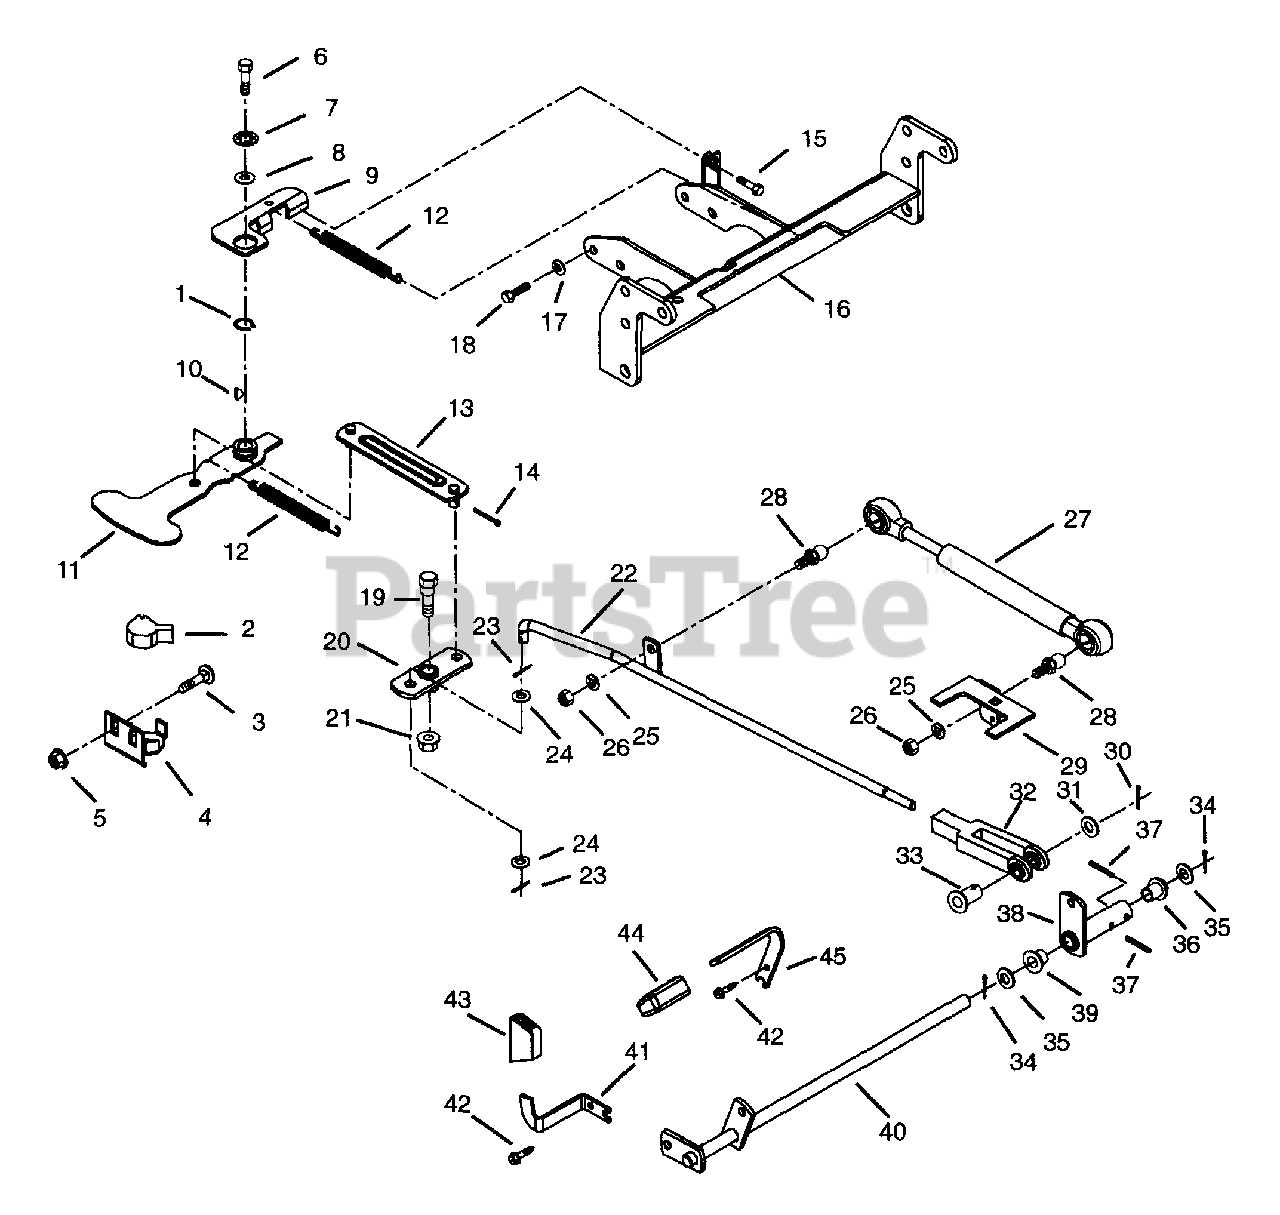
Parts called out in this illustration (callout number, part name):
1	RG-RTNG-EXT .875X.042
3	BLT-RDHDSQNK .312-18X.62SHTPL
4	MOUNT - MAGNET
5	NUT-LK .312-18 GR A PL
6	BLT-HEX .25-20X1.50 PL GR5
7	WSHR-LK-EXT. 250 ID
8	WSHR-FL-STL.312X.734X.065PL
9	ARM, NEUTRAL
10	KEY-WDRF .125X.500X.203 SAE 3
11	ARM, NEUTRAL CONTROL
12	SG-TENS .085X.60X5.13 WLD8.3
13	LINK, SHIFT
14	PIN-COTR .12X.75 PL
15	BLT-HEX .31-18X.75 PL GR2
16	MOUNT, TORQUE
17	WSHR-LK .312X.097 PL HVY
18	BLT-HEX .31-18X.75 PL GR5
19	BLT-SHLDR .38-16X1.25
20	BELLCRANK - SHIFT
21	NUT-LK-CTR .375-16 GR A PL
22	ROD - SHIFT
23	PIN-COTR .09X.75 PL
24	WSHR-FL-STL.406X.812X.065PL
25	WSHR-LK .312X.097 PL HVY
26	NUT-HEX .312-18
27	DAMPER - HYDRAULIC
28	STUD- BALL
29	BRACE-DAMPER
30	PIN-COTR .09X.75 PL
31	WSHR-FL-STL .390X.750X.125 PL
32	YOKE, .312-24 X 2.25
33	PIN-CLEV .312X.822 HDND PL
34	PIN-COTR .12X1.0 PL
35	WSHR-FL-STL .520X.827X.062 YZ
36	BSHG-FLG .515X.750X.745X1.00NY
37	PIN-GRV .188X1.25 TP A
38	ARM & HUB - SHIFT
39	BSHG-FLG .502X1X.750
40	SHAFT - PEDAL
41	PEDAL - REVERSE
42	SCR-TAP .375-16X .50 HWH PL TR
43	COVER - PEDAL - REVERSE
44	COVER - PEDAL - FORWARD
45	PEDAL - FORWARD
46	RG-RTNG-EXT .875X.042
